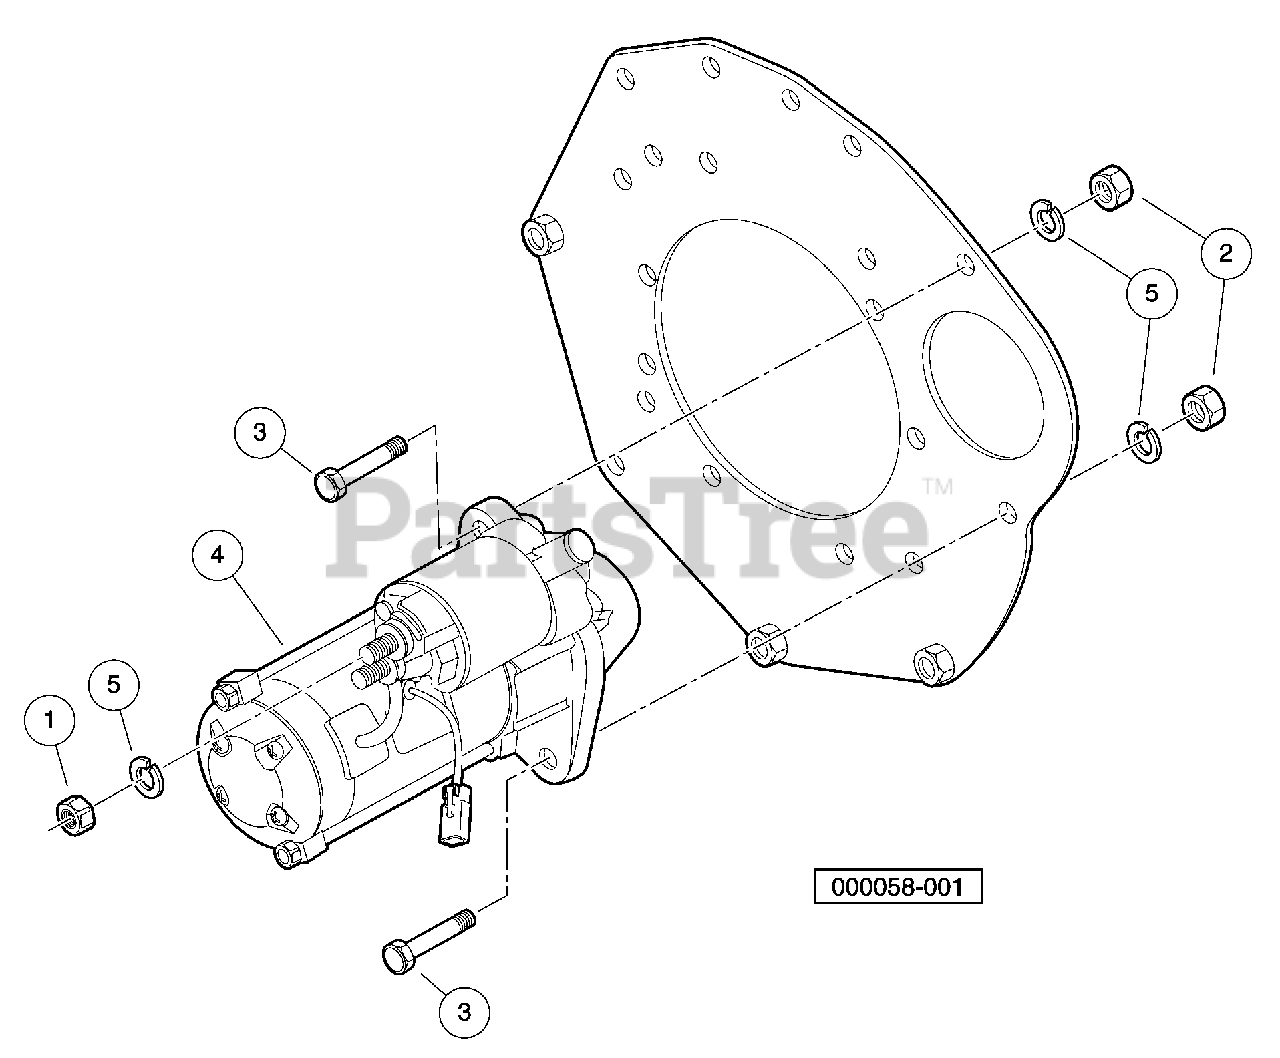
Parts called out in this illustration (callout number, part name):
1	Nut, D722, Starter
2	Nut, M8, Plate
3	Bolt, M8 X 1.25 X 28
4	Motor, Starter
5	Washer, Spring, D722, Starter
